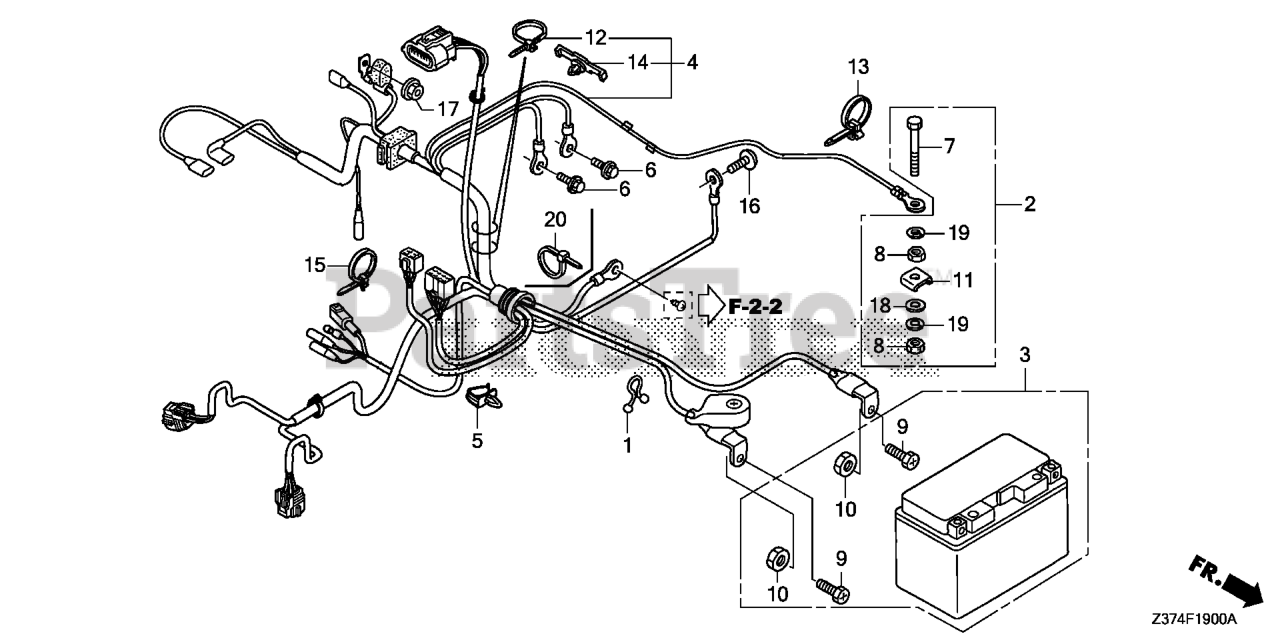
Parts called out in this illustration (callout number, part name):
2	TERMINAL SET, GROUND
3	BATTERY (YTZ14S) (YUASA) (MSDS)
4	WIRE HARNESS ASSY., ENGINE
5	CLIP B, HARNESS
6	BOLT, FLANGE (6X12) (CT200)
7	BOLT, HEX. (6X28)
8	NUT, HEX. (6MM)
9	BOLT, BATTERY TERMINAL
10	NUT, BATTERY TERMINAL
11	RETAINER (6MM)
12	STRAP, CABLE (118MM) *NH1L* (Honda Code 1170653). (BLACK)
13	STRAP, CABLE (105MM) *NH1* (Honda Code 1685536). (BLACK)
14	CLIP, WIRE HARNESS (50MM) (BLACK)(HARNESS TAPING)
15	CLIP B, HARNESS BAND (129.4MM) (DARK BROWN)
17	NUT-WASHER (8MM)
18	WASHER, PLAIN (6MM)
19	WASHER, SPRING (6MM)
20	TIE, CABLE (C)
